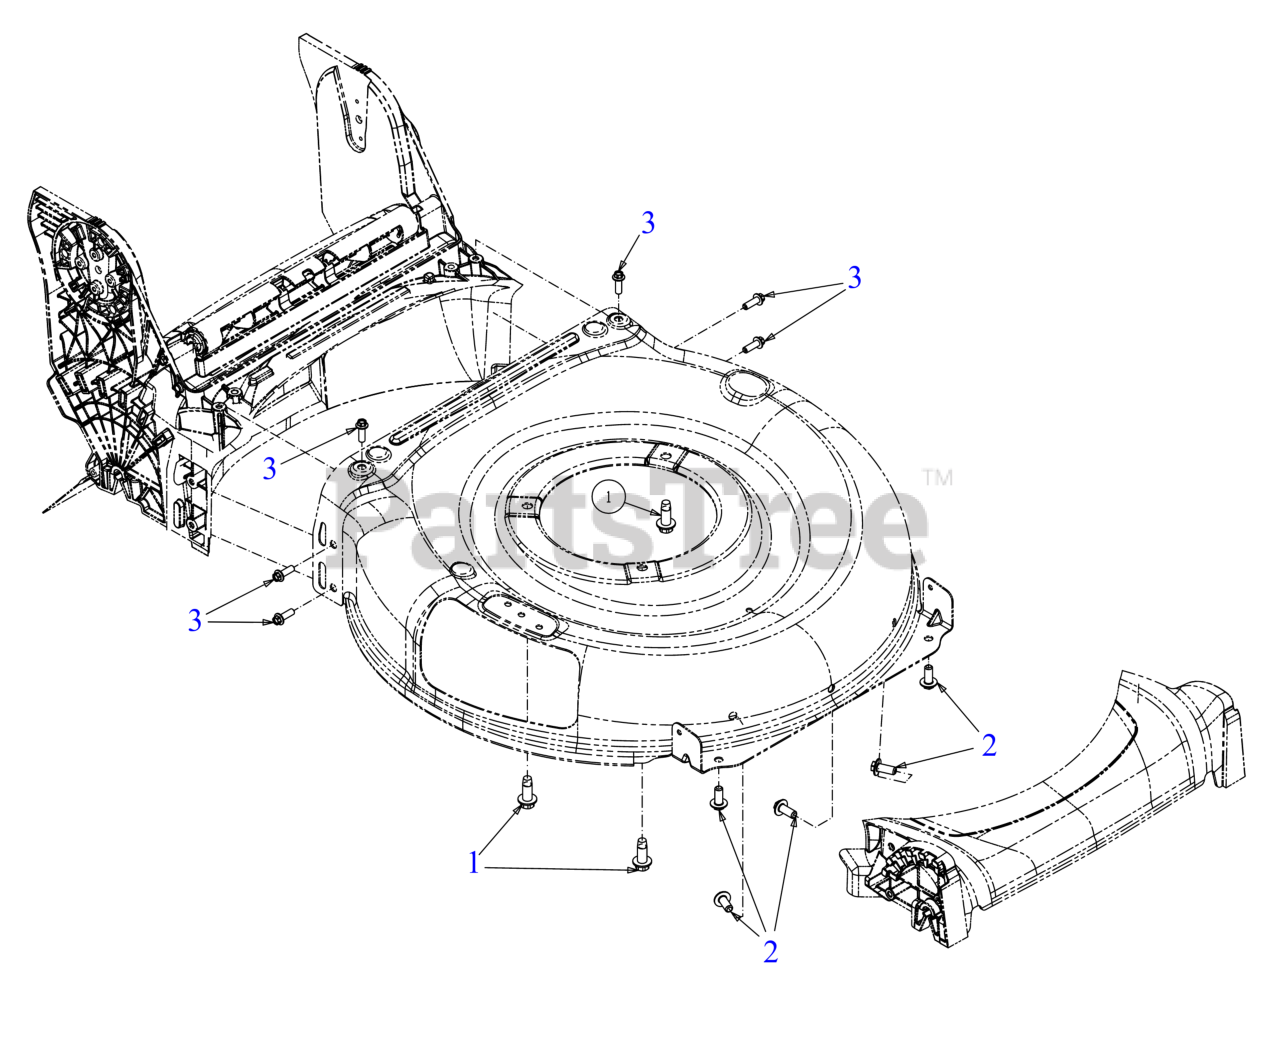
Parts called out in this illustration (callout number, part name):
1	SCREW 3/8-16 x 1
2	SCREW 5/16-14 x .750
3	SCREW 1/4 x .750
